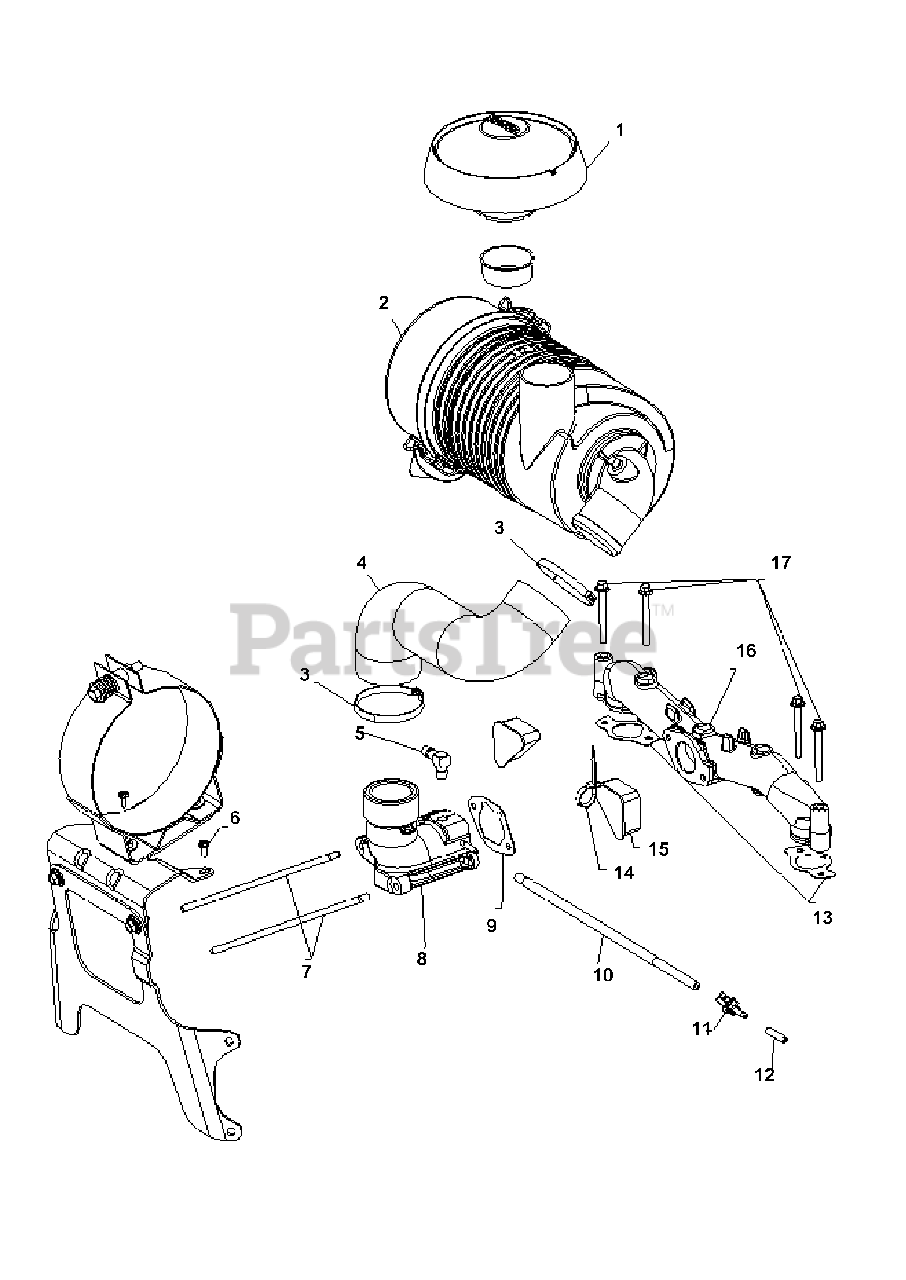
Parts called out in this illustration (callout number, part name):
4	Air Cleaner Hose
5	Hose Connecter
6	Screw, #8-18 x 1/2
7	Stude, M6 x 1.0 x 180
9	Air Cleaner Base Gasket
10	Evaporative Hose
11	Evaporative Connector
13	Intake Manifold Gasket
15	Blower Housing Cover
16	Intake Manifold
17	Screw, M6 x 1.0 x 55
